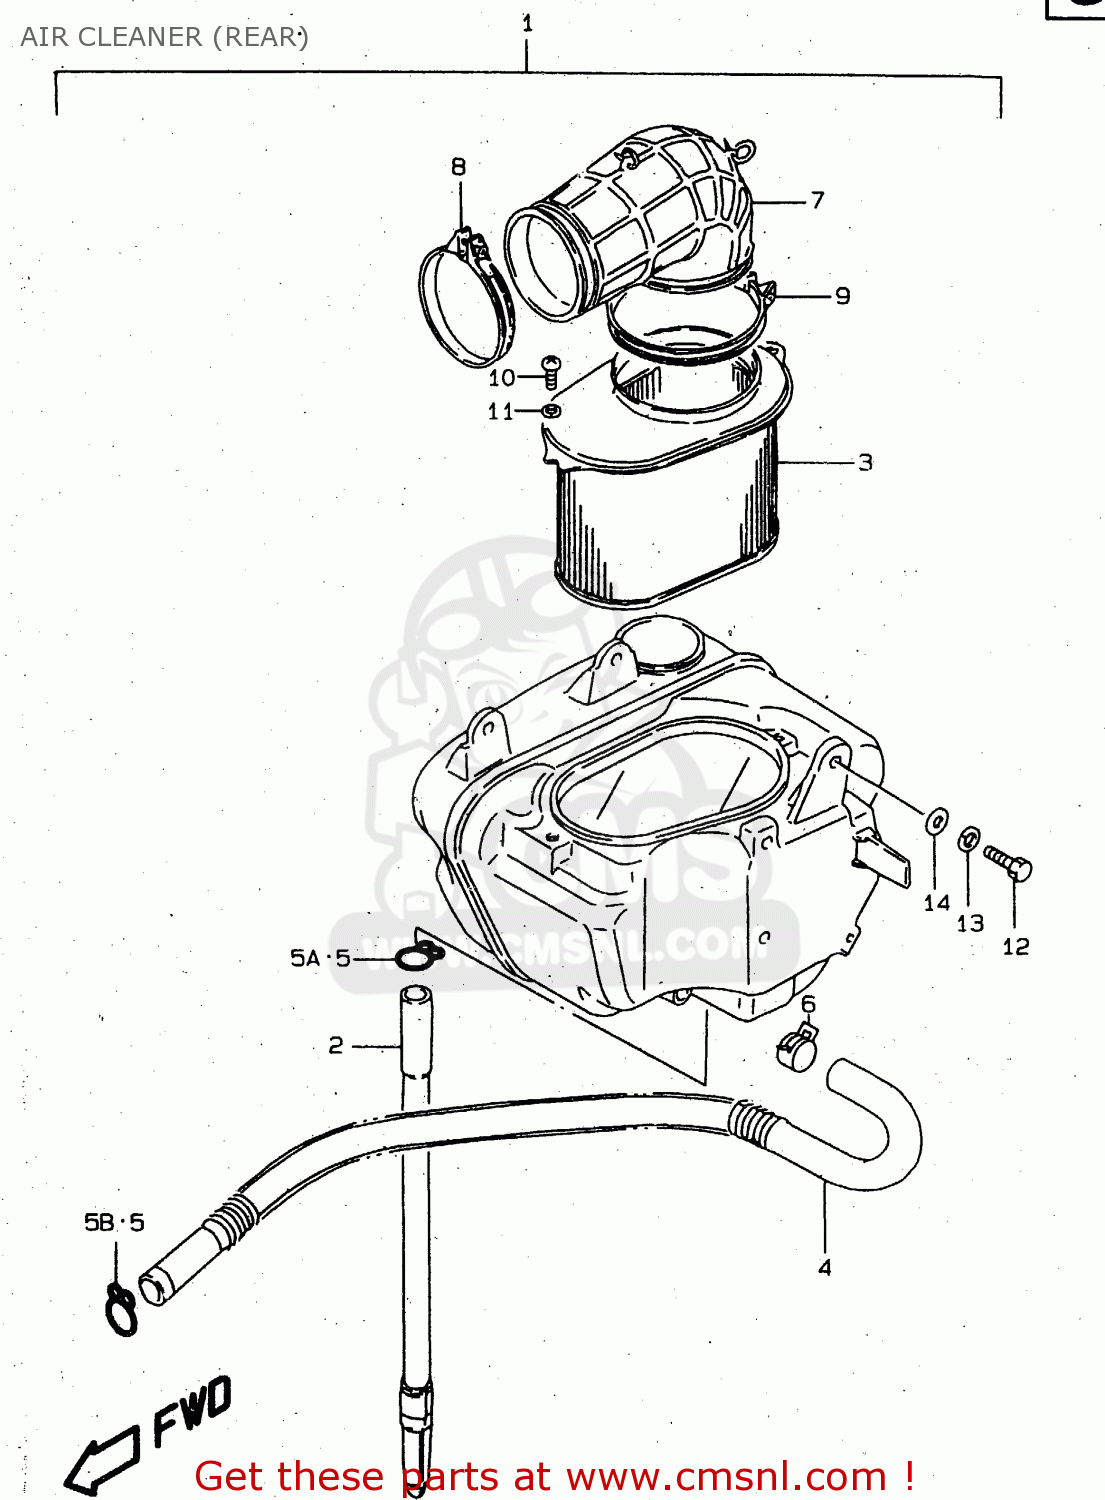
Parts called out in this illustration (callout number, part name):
1	CLEANER ASSY,AIR RR
2	TUBE,DRAIN
3	FILTER ASSY
4	TUBE SET,BREATHER
5	CLIP
5A	CLIP
6	CLIP
7	TUBE,AIR CLEANER OUTLET
8	CLAMP
9	CLAMP
10	SCREW
11	LOCK,WASHER
12	BOLT
13	WASHER,LOCK
14	WASHER(6.5X16X1.2)
